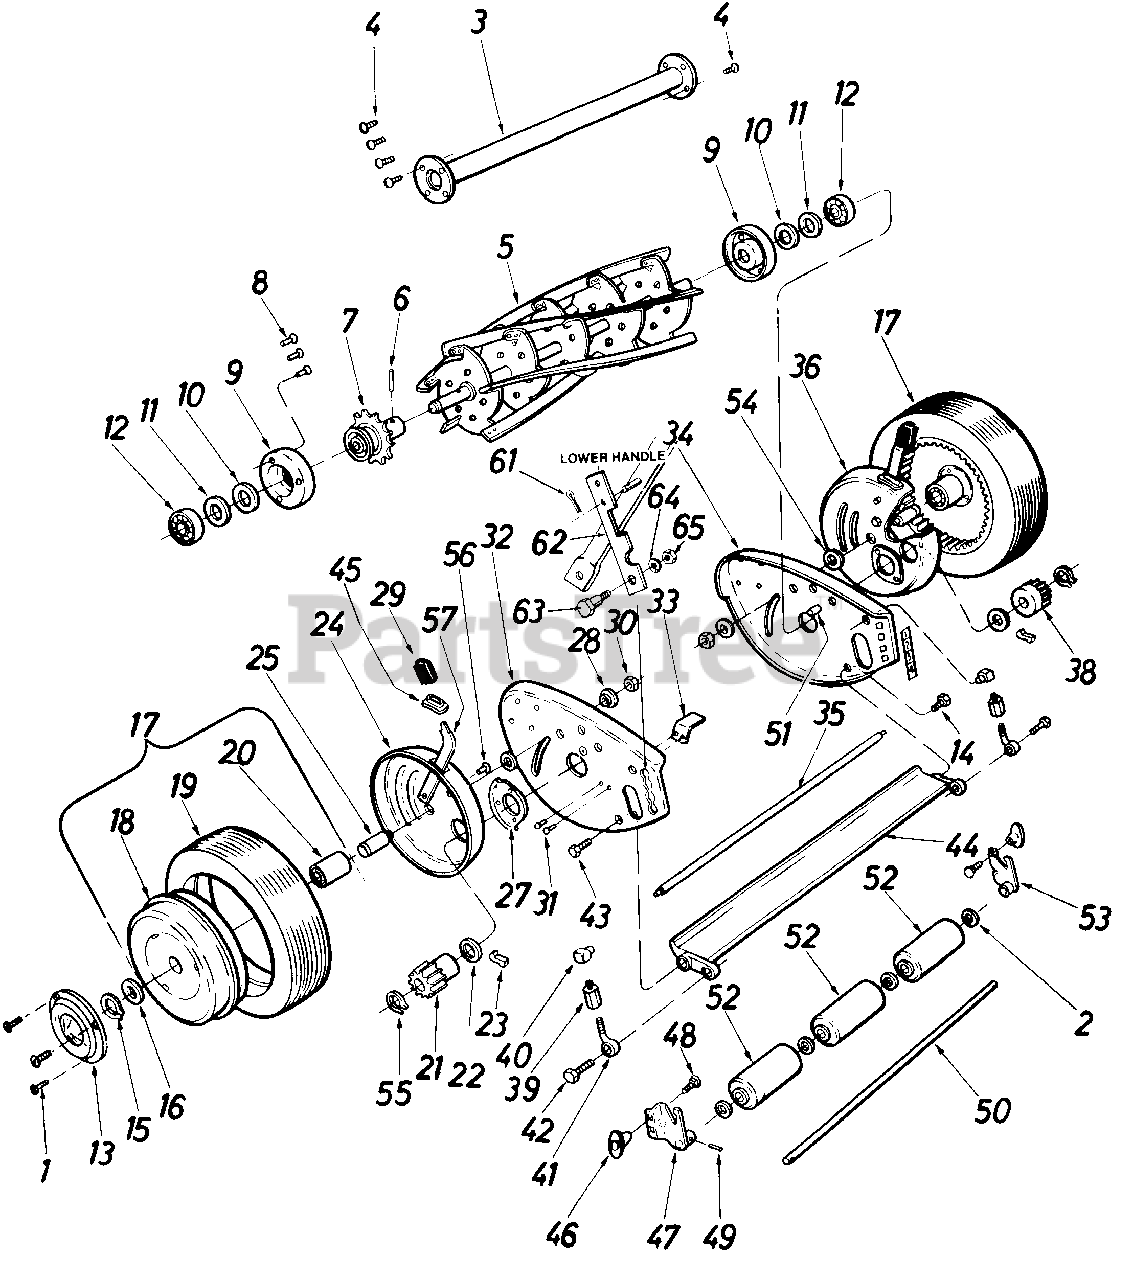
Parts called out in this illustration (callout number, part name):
1	Ph. Hd. Scr. #10-32 x .62" Lg.*
2	Roller Washer
3	21" Spacer Tube Ass'y.
4	Rivet-3/16 x 3/8 "
5	21" Reel Ass'y.
6	Roll Pin
7	Sprocket Anti-Wind Cup, and Hub Ass'y.
8	Rivet 3/16 x 13/32"
9	Retainer
10	Felt Washer
11	Felt Retainer
12	Beari ng
13	Hub Cap
14	Scr.-Cutter Bar L.H. Thd.
15	Retaining Ring
16	Washer
17	Wheel Ass'y.-Comp.
18	Wheel Ass'y. w/Bearing
19	Tire 10.25 x 2.50
20	Bearing
21	Pinion Gear-R.H.
22	Felt Washer
24	Gear Housing-L.H.
27	Retainer
28	Bushing
29	Wheel Adj. Knob
30	Hex Lock Nut
31	Hex Sems Scr. 10-32 x .375" Lg.
32	End Plate w/Trunnions
33	Scraper
34	End Plate wlTrunnions
35	End Plate Spacer
36	Gear Housing
38	Pinion Gear
39	Turnbuckle Nut
40	Trunnion
42	Screw
43	Scr.-Cutter Bar-R.H . Thd.
44	21" Cutter Bar Ass'y.
45	Dust Cover
46	Roller Adj. Knob
47	Roller Brkt. Ass'y.-L.H.
48	Hex Scr. 5/16-18 x .62" Lg.
49	Roll Pin
50	Roller Shaft
51	Trunnion
52	Roller
53	Roller Brkt. Ass'y.-R.H.
54	Washer
55	Retaining Ring
56	Hex Scr. #10-32 x .375" Lg.
57	Spring and Trunnion Ass'y.
61	Internal Cotter Pin
62	Handle Brace
63	Shld. Bolt 5/16-18 Thd.
64	L-Wash. 5/16" Scr.
65	Hex Nut 5/16-18 Thd.
